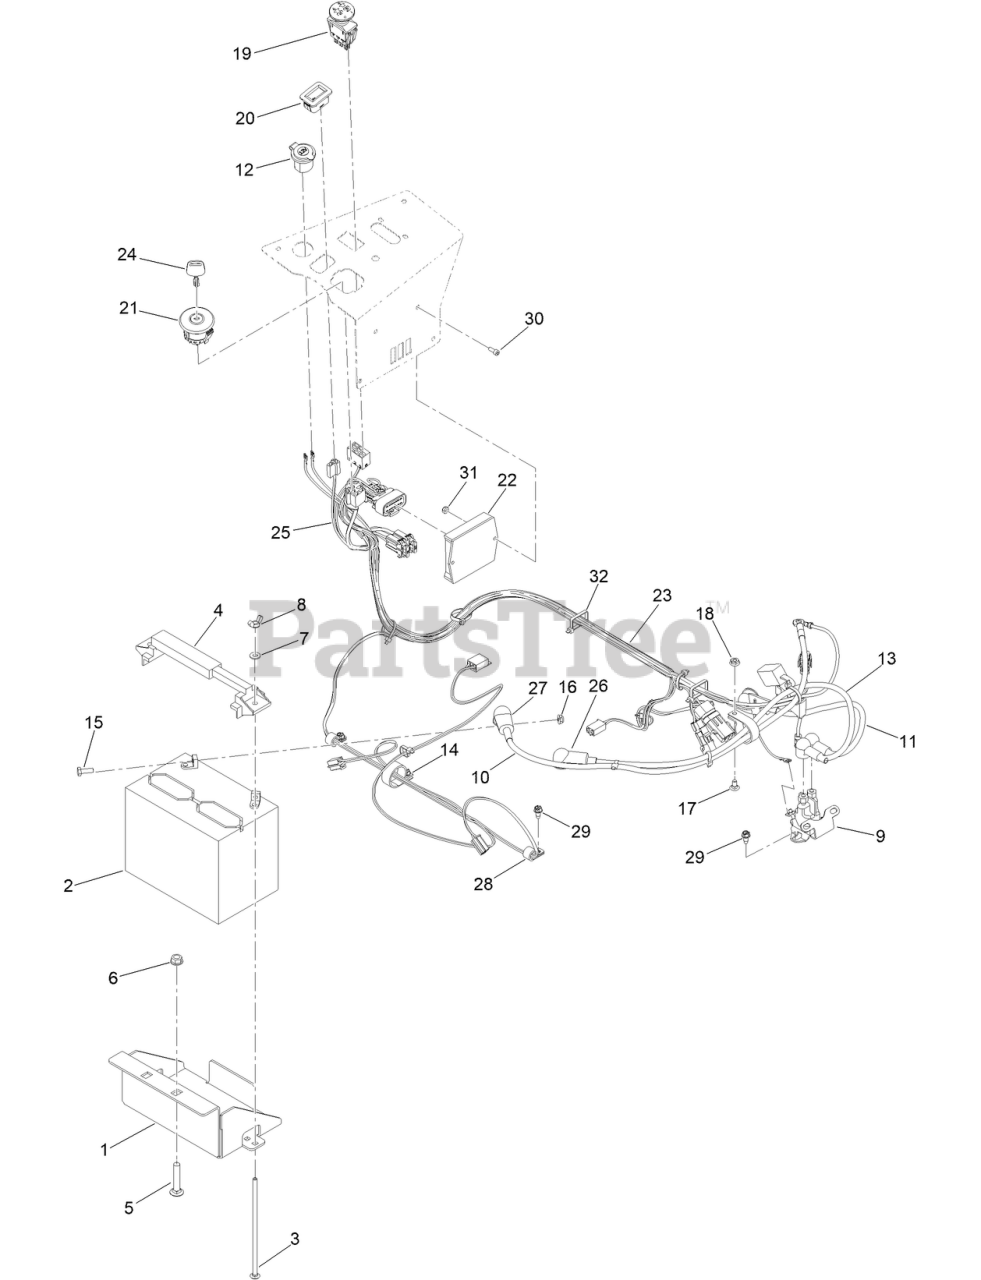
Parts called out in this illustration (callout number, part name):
1	MWR BATTERY BOX
2	12 VOLT START BATTERY 300CCA
3	1/4-20 X 7 CARRIAGE BOLT ZINC
4	BATTERY HOLD DOWN
5	SCREW-CARR
6	NUT-HHF, WHIZ
7	WASHER-FLAT
8	NUT-WING
9	HEAVY DUTY START SOLENOID
10	MWR NEGATIVE CABLE 28
11	MWR START WIRE 12
12	12 VOLT AUXILLIARY PLUG
13	MWR POSITIVE BATTERY CABLE 25IN
14	1-1/4IN CUSHIONED LOOP CLAMP BLACK
15	SCREW-HH
16	NUT-HF
17	SCREW-CARR
18	1/4-20 HEX FLANGE NUT
19	PTO SWITCH
20	HOUR METER
21	IGNITION SWITCH
22	INTERLOCK MODULE
23	BRIGGS 25HP/27HP/ 726CC HARNESS
24	2023 MWR KEY
25	MWR KEYSWITCH JUMPER HARNESS
26	3.15 LGTH STRAIGHT INSUL TERM COVER RED
27	STRAIGHT INSULATING TERMINAL COVER
28	CLAMP-R
29	SCREW-HWH
30	10-24 X 1/2 SOCKET C/S 18-8 SS
31	NUT-LOCK
32	TIE-CABLE
